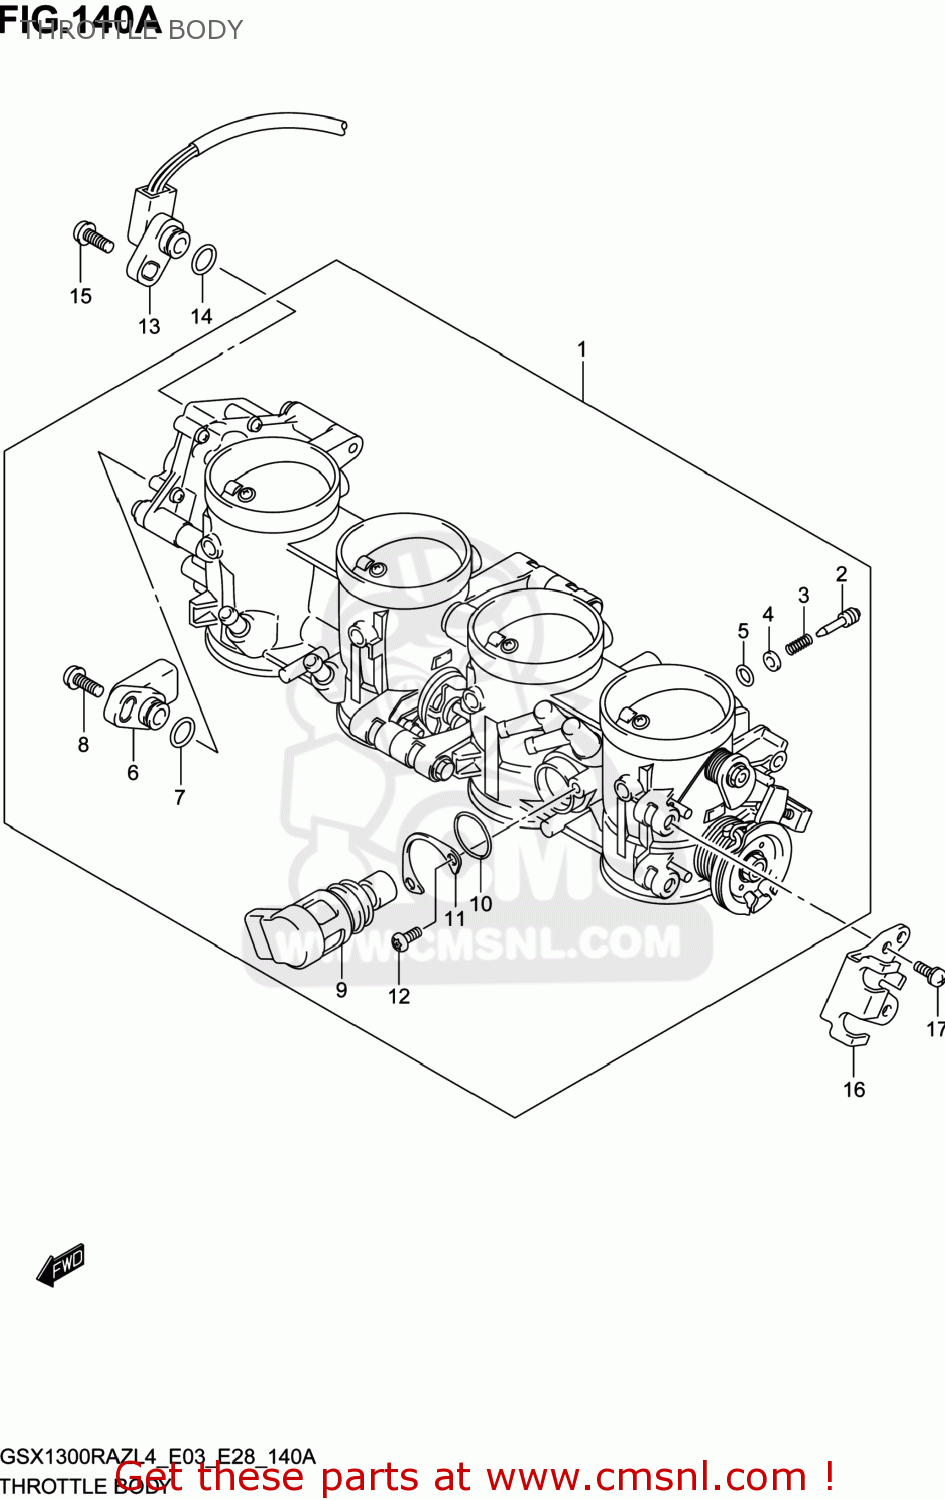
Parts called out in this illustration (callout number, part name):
1	BODY ASSY,THROTTLE
2	SCREW,AIR ADJUST
3	SPRING
4	WASHER
5	O RING
6	SENSOR ASSY,THROTTLE MAIN
7	O RING
8	SCREW
9	VALVE ASSY,ISC
10	O RING
11	PLATE,ISC VALVE
12	SCREW
13	SENSOR ASSY,THROTTLE NO.1
14	O RING
15	SCREW
16	PLATE,STAY
17	SCREW
